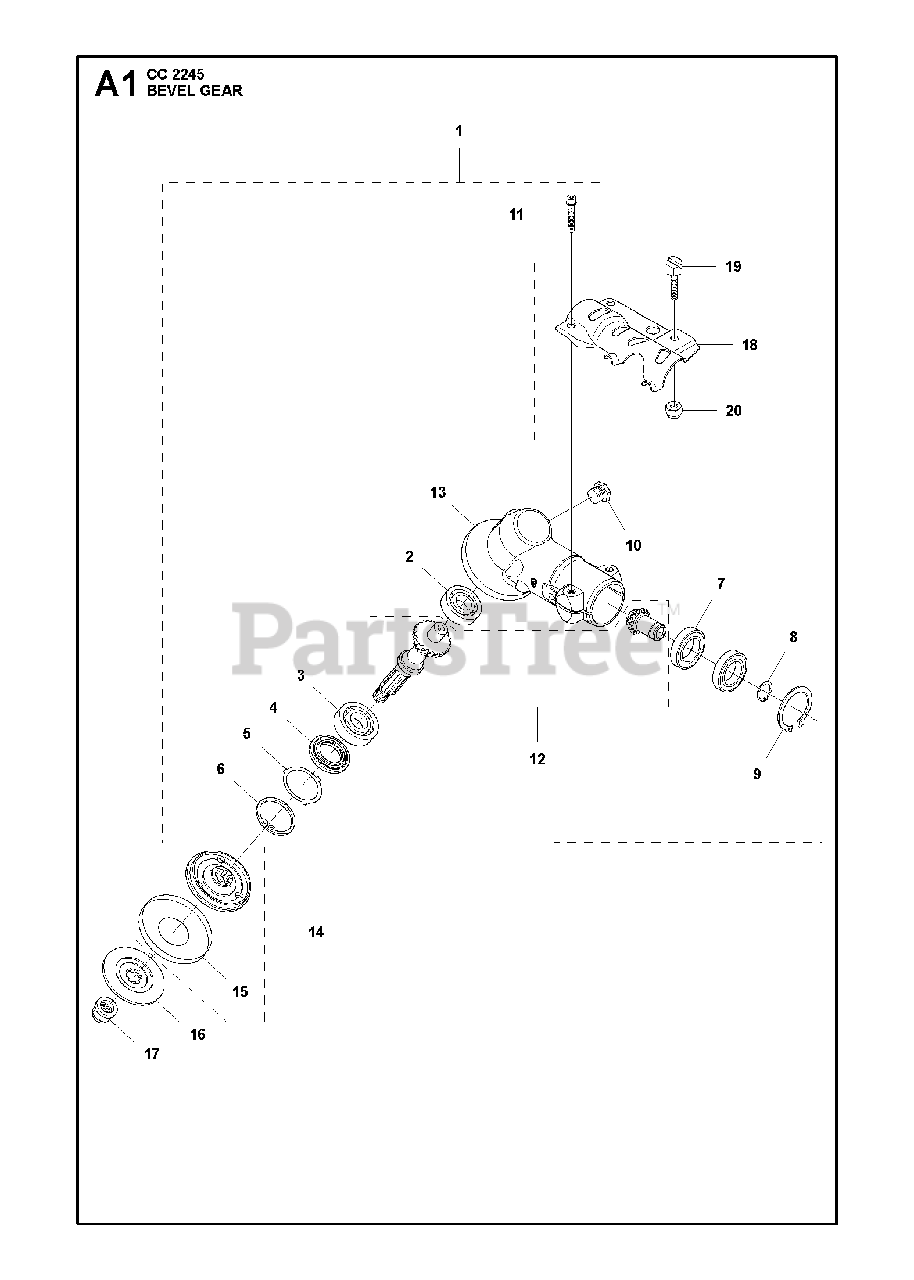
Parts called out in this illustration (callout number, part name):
1	GEAR ASSY
2	BALL BEARING
3	BALL BEARING
4	SEAL
5	WASHER
6	RETAINING RING SGH 35
7	BALL BEARING
8	RETAINING RING SGA 15
9	RETAINING RING
10	PLUG
11	SCREW
12	SPARE PARTS KIT
13	GEAR HOUSING
14	RP CARRIER
15	RP TUBE INSERT
16	SUPPORT FLANGE
17	NUT BLADE
18	ATTACHMENT PLATE
20	LOCKNUT M6
